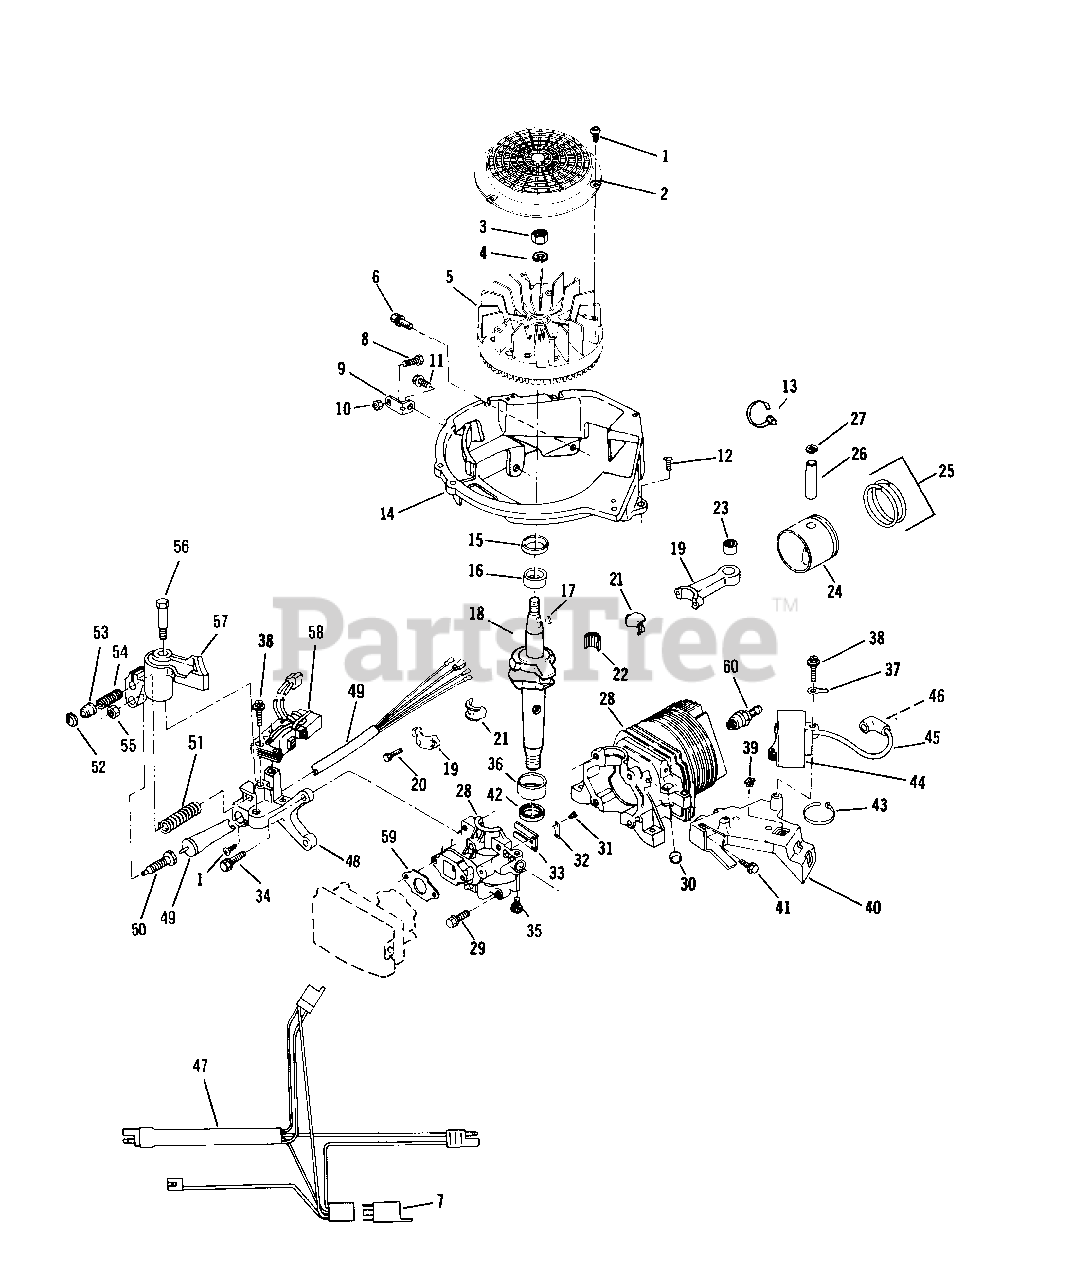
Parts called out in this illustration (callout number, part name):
1	Screw-Flywheel Screen and Switch
2	Screen-Flywheel
3	Nut-Flywheel
4	Lockwasher
5	Flywheel
6	Screw
7	Relay
8	Bolt-Brace-Alternator Bracket
9	Brace-Alternator Bracket
10	Locknut-Brace-Alternator Brkt.
11	Screw
12	Screw-Shroud Base to C.D. Bracket
13	Tie Strap
14	Base-Shroud
15	Oil Seal-Upper
16	Bearing-Upper
17	Key-Flywheel
18	Crankshaft
19	Connecting Rod Assembly
20	Screw-Cap
21	Liner Split
22	Needle Bearing Set
23	Bearing Assembly
24	Piston and Ring Set
25	Ring Set
26	Wrist Pin
27	Retaining Ring
28	Cylinder and Crankcase Cover Assembly
29	Screw-Cover to Crankcase
30	Plug
31	Screw-Reed to Crankcase Cover
32	Plate-Reed Hold Down
33	Reed
34	Screw-Alternator and Brake Mounting Bracket
35	Set Screw-Starter Assembly
36	Bearing-Lower
37	Terminal-Ground Lead
38	Screw-C.D. Mounting
39	Grommet-C.D. Bracket
40	Bracket-Ignition Mounting
41	Screw
42	Oil Seal-Crankshaft
43	Tie Strap
44	C.D. Ignition Module and Lead Assembly
45	High Tension Lead and Cover Assembly
46	Spring Terminal
47	Wire Harness Assembly
48	Bracket-Alternator and Brake
49	Brake Switch Assembly
50	Plunger
51	Spring-Brake
52	Retainer
53	Actuator-Brake Lever
54	Spring-Cable Retainer
55	Nut
56	Bolt-Shoulder
57	Brake Assembly
58	Alternator Assembly
59	Gasket-Carburetor to Crankcase Cover
60	Spark Plug
